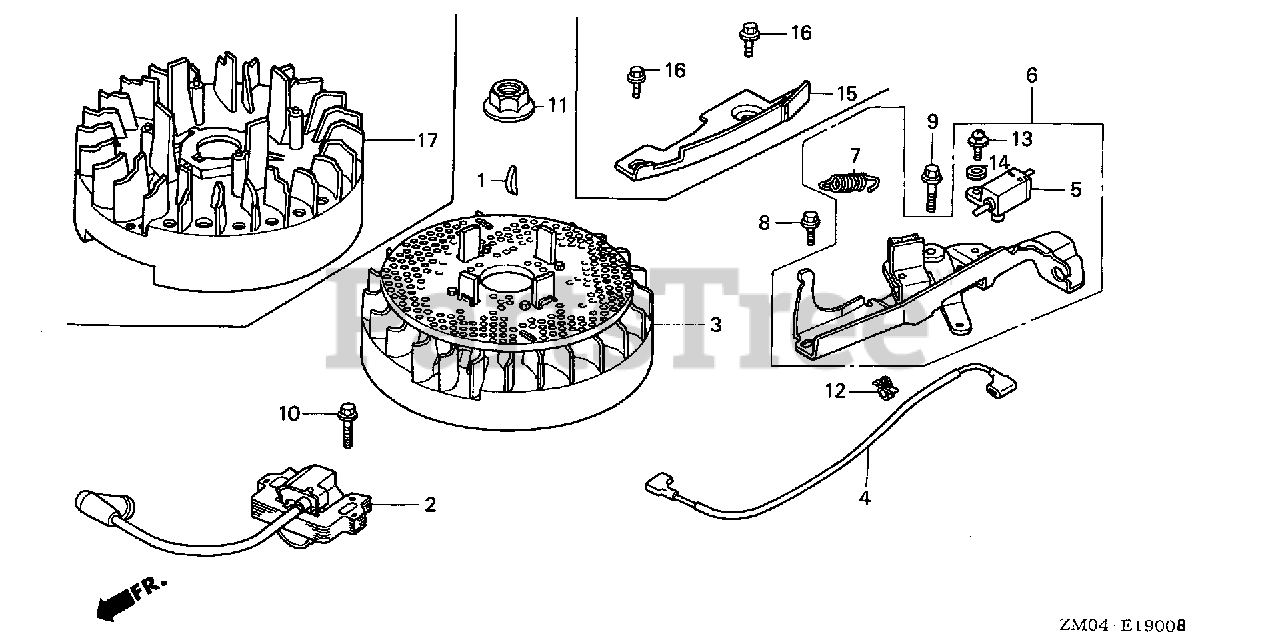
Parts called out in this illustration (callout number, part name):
1	KEY, SPECIAL WOODRUFF (25X18)
2	COIL ASSY., IGNITION
3	FLYWHEEL ASSY.
4	WIRE, STOP SWITCH
5	SWITCH ASSY., ENGINE STOP (N.C)
6	BRAKE ASSY.
7	SPRING, BRAKE LEVER
8	BOLT, FLANGE (6X14)
9	BOLT, FLANGE (6X23)
10	BOLT, FLANGE (6X20) (CT200)
11	NUT, SPECIAL (14MM)
12	CLIP, CABLE (A)
13	SCREW-WASHER (4X12)
14	WASHER, PLAIN (4MM)
